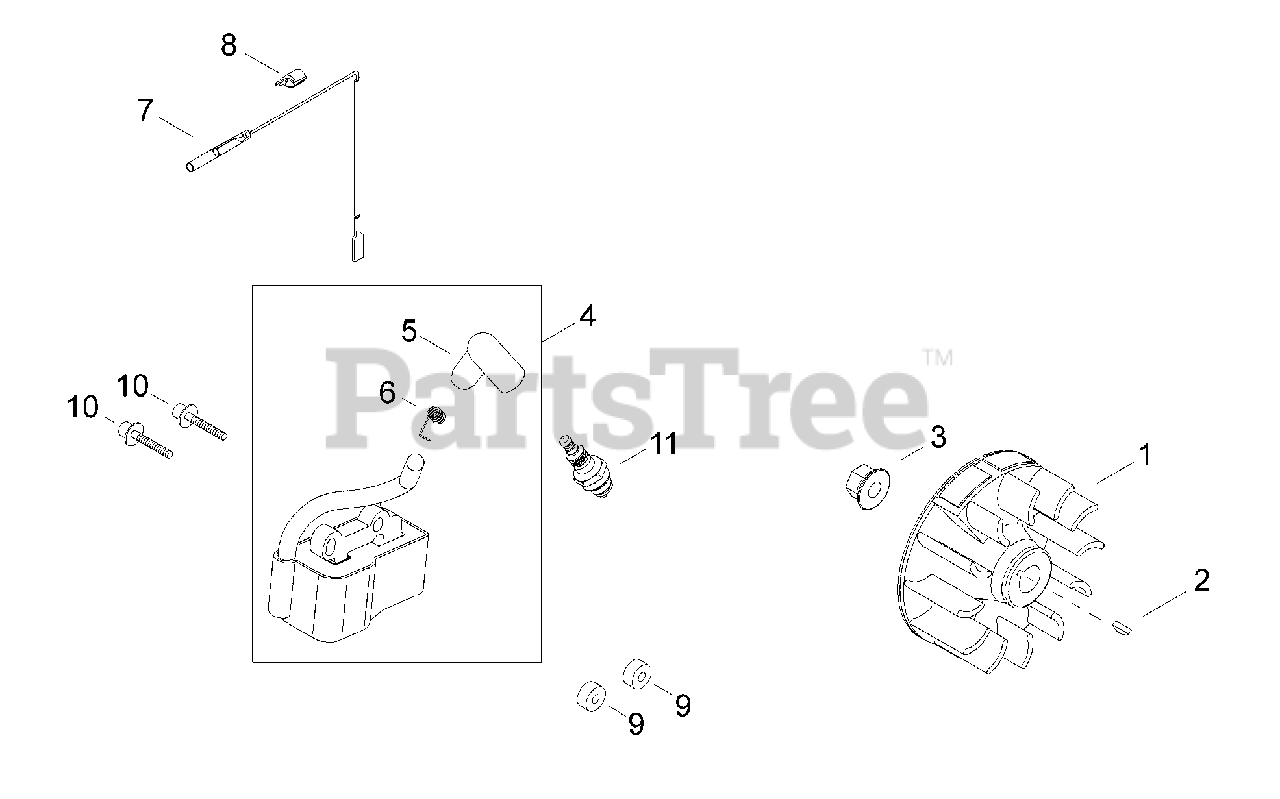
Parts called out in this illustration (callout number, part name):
1	FLYWHEEL
2	KEY, WOODRUFF 3×10
3	NUT M8
4	COIL ASSY, IGNITION
5	CAP, SPARK PLUG
6	TERMINAL, SPARK PLUG
7	LEAD - IGNITION
8	GROMMET, LEAD
9	INSULATOR 4.2×11×6
10	BOLT M4×26
11	SPARK PLUG - CMR5H
